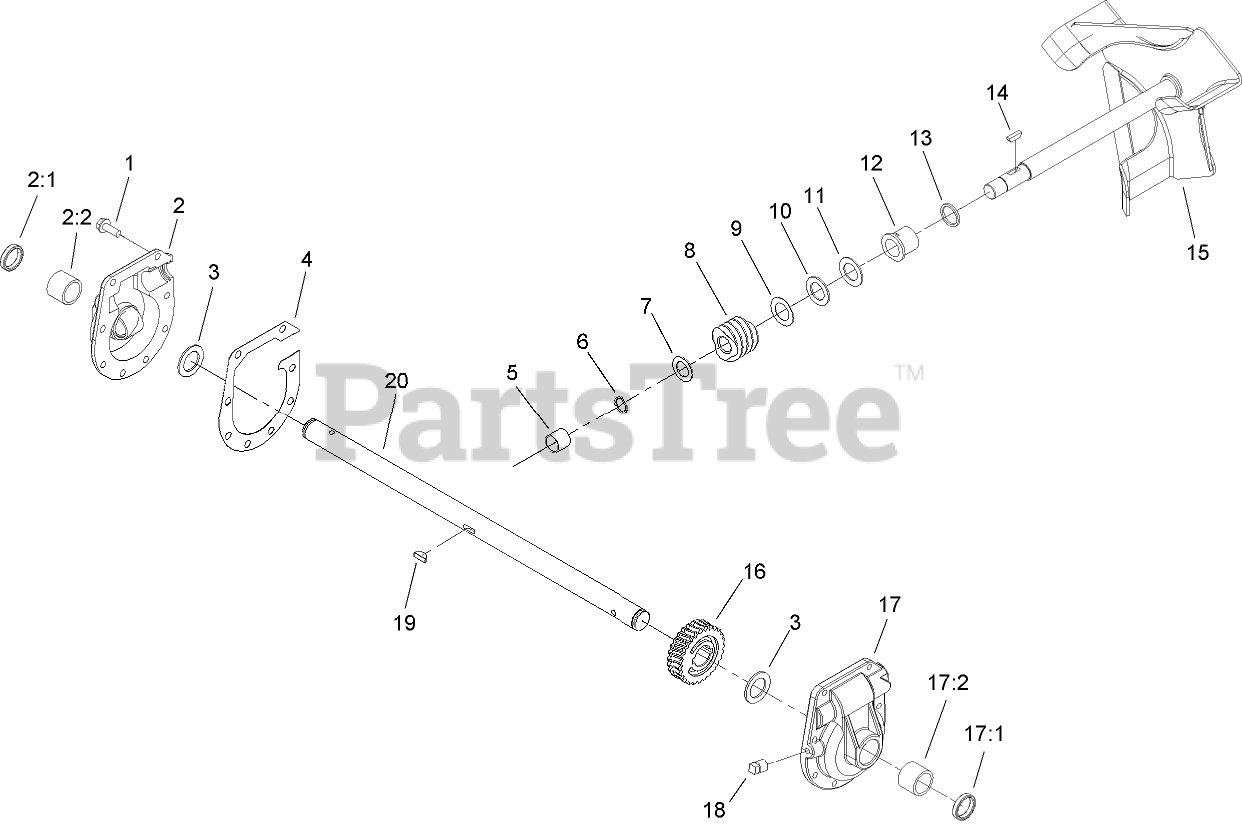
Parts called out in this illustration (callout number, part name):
1	SCREW-TAPTITE
2	RH BUSHING CASE ASM
2:1	SEAL-OIL
2:2	BUSHING-SLEEVE
3	WASHER-THRUST
4	GASKET-CASE, GEAR
5	BUSHING
6	Ring-Snap
7	WASHER-THRUST
9	WASHER-THRUST
10	BEARING-THRUST
11	WASHER-THRUST
12	BUSHING-INPUT
13	RING-QUAD
14	KEY-WOODRUFF
15	IMPELLER SHAFT ASM
16	GEAR-WORM, 27T
17	LH BUSHING CASE ASM
17:1	SEAL-OIL
17:2	BUSHING-SLEEVE
18	PLUG-PIPE, SQH
19	KEY-WOODRUFF
20	SHAFT-AUGER
